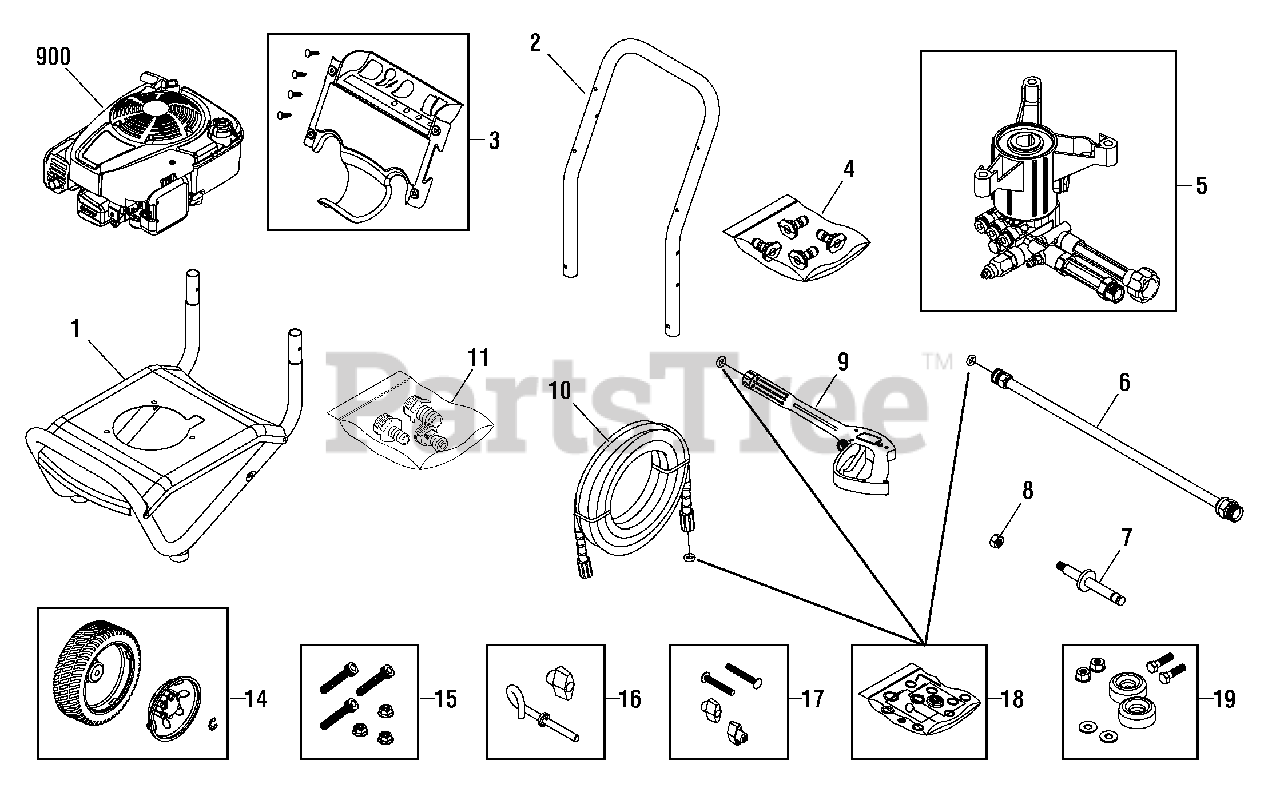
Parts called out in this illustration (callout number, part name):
4	KIT, QC Nozzles
6	EXTENSION, QC
9	GUN
11	KIT-GARDEN HOSE
14	KIT, Wheel
15	KIT, Hardware, Pump Mounting
17	KIT, Hardware, Handle
19	MOUNT, Vibration
900	* ENGINE
